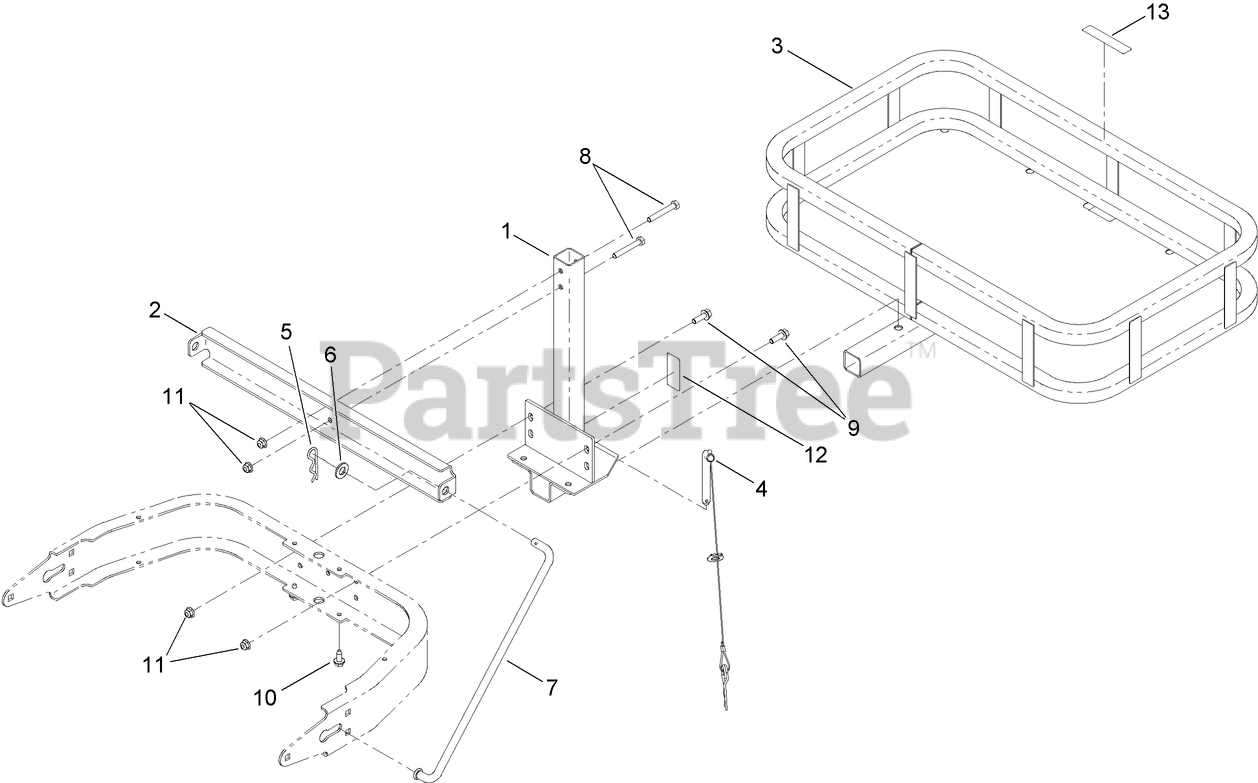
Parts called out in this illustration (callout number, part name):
1	MOUNT-TRAY
2	BRACKET-SUPPORT
3	TRAY-CARRIER
4	PIN-ROPS
5	PIN-HAIR
6	WASHER-FLAT
7	ROD-SUPPORT
8	SCREW-HH
9	SCREW-HHF
10	SCREW-HWHTF
11	NUT-HF, NI
13	DECAL-MAXIMUM WEIGHT
